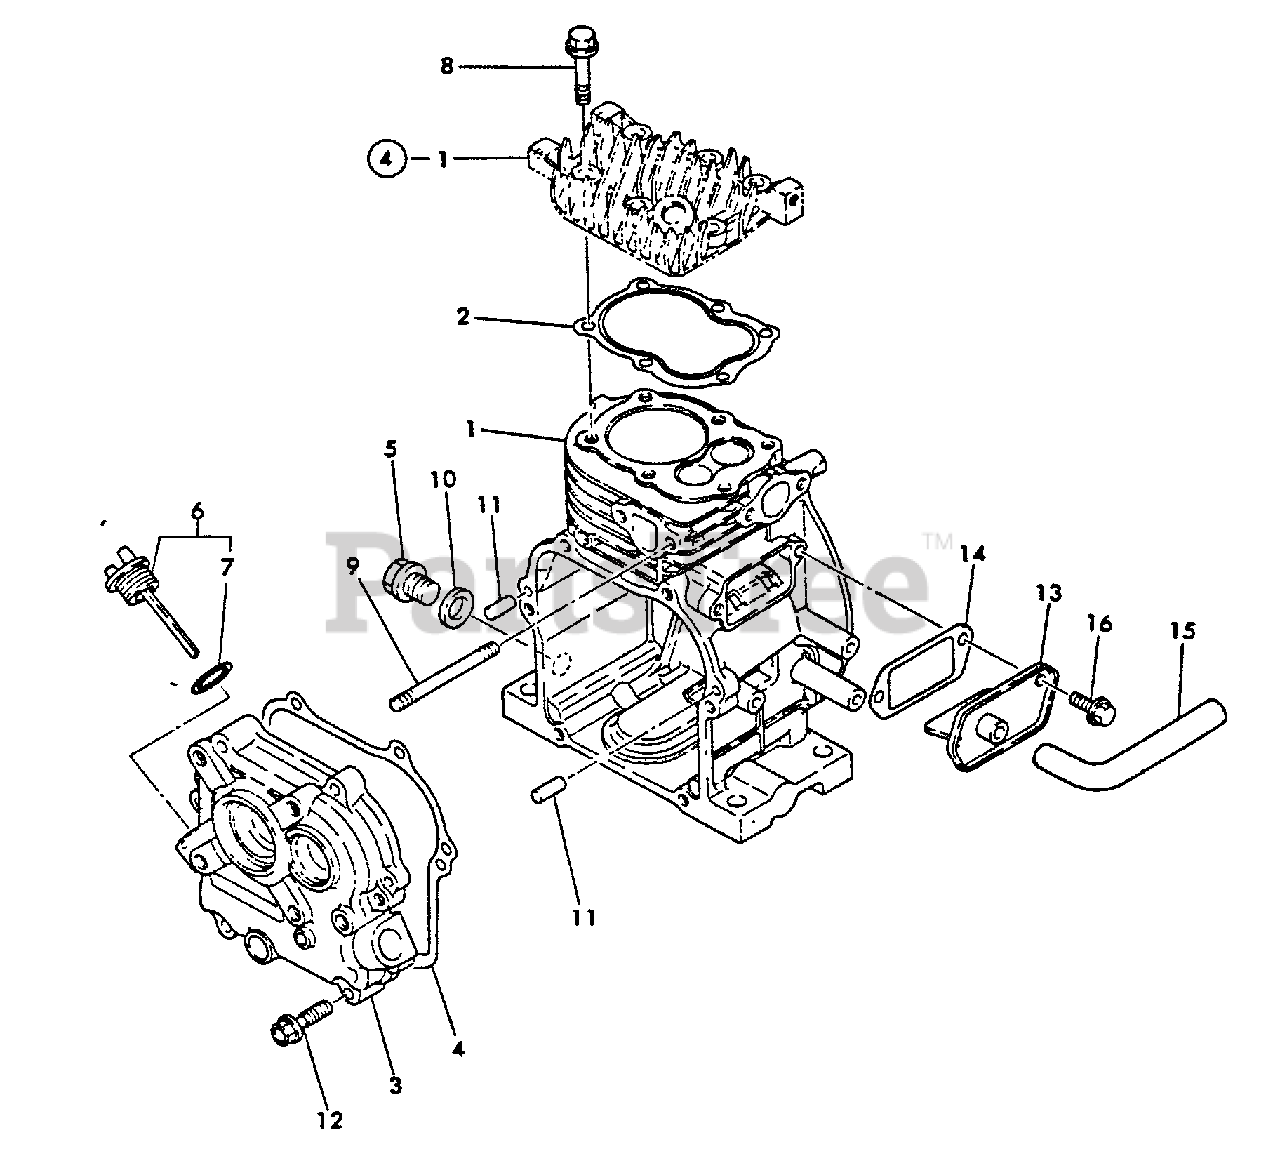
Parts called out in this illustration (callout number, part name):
1	CYLINDER ASSY
2	GASKET, CYLINDER
3	COVER, CRANKCASE
4	GASKET, CRANKCASE
5	PLUG, DRAIN
6	CAP, OIL
7	O-RING 1A P-15.0
8	BOLT - 6×35
9	BOLT - 6×70
10	GASKET
11	PARALLEL PIN 6×16
12	BOLT - 6×30
13	BREATHER ASSY
14	GASKET, BREATHER
15	PIPE, BREATHER
16	BOLT - 6×8 -- PLATED
